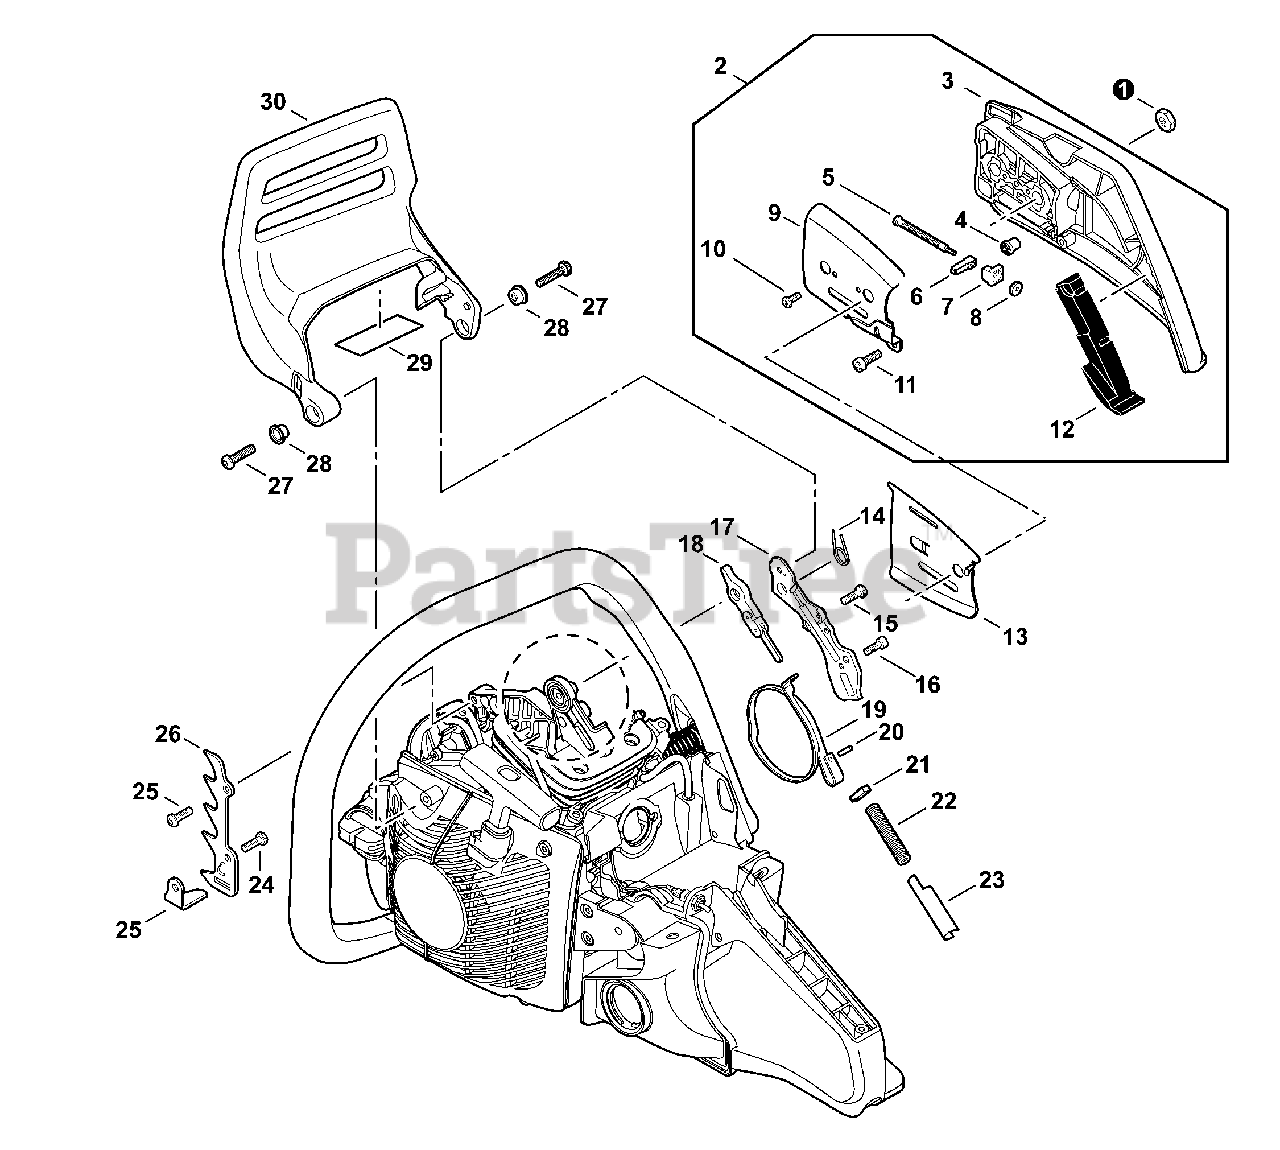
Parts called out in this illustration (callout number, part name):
1	NUT, FLANGE M8×1.25
2	GUARD KIT, SPROCKET
3	GUARD, SPROCKET
4	GEAR, BEVEL
5	SCREW, CHAIN TENSION 63 MM
6	TENSIONER, CHAIN
7	COLLAR 8
8	GEAR, BEVEL
9	PLATE, GUIDE - OUTER
10	SCREW 3×6
11	BOLT, TORX 4×12
12	CUSHION
13	PLATE, GUIDE - INNER
14	SPRING, TORSION
15	BOLT, TORX 5×16
16	BOLT, TORX 4×12
17	COVER, BRAKE
18	CONNECTOR, BRAKE
19	BAND, BRAKE
20	PIN, SPRING 3x-9.8
22	SPRING, COMPRESSION Ø12×70.5
23	PLATE, SIDE
24	BOLT, TORX 5×16
25	CHAIN CATCHER
26	SPIKE, BUMPER
27	BOLT, TORX 5×16
28	COLLAR 11.2×16.2×T0.6
29	SHIELD, HEAT 75×27×0.15
30	LEVER, BRAKE
